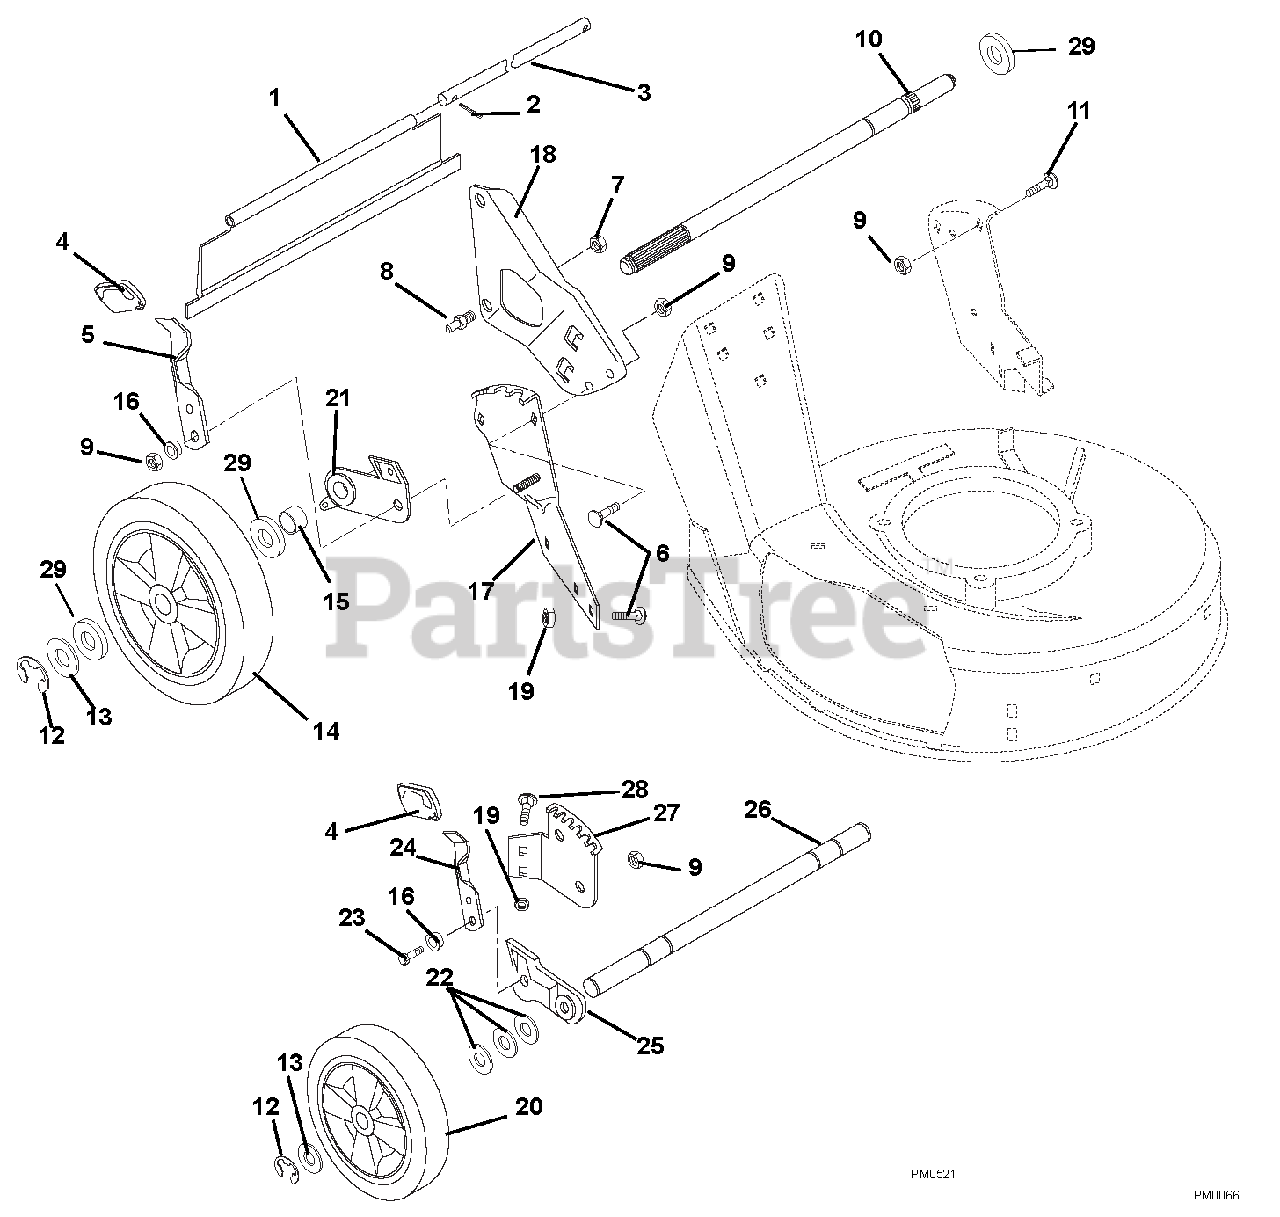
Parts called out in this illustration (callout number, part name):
1	REAR PROTECTIVE GUARD, S.P.
2	@PIN-CTR .06X.50 EXTPRSQCT YWZ
3	ROD
5	LEVER, HEIGHT ADJUSTMENT
6	@BLT-RHDSSQNK .31-18X.62 G5YZ
7	@NUT-LK-CTR .38-16 YWZC
8	HANDLEBAR STUD
9	@NUT-LK-TOP-FLG .31-18 YWZC
10	REAR AXLE,5/8 DIA
10	REAR AXLE-PUSH MOWER MM
11	BLT-RDHDSQNK .31-18X1.0 SHTYZ
12	RG-RTNG-EXT .500X.042 (E)
13	WSHR-FL-STL .505X.880X.072 YWZ
14	WHL, LH 10.50"
14	WHL, RH 10.50"
14	10 1/2 TIRE SKIN
14	TIRE, REAR 10X1.75 #6 GRAY
15	SPACER TUBE, SELF PROPEL
15	SPACER TUBE PUSH RH
16	BSHG-FLG .32X.500X.344X.880
17	QUADRANT, REAR LH
17	QUADRANT, REAR RH
18	RH HANDLEBAR MTG. BRKT
18	LH HANDLEBAR MTG. BRKT
19	@NUT-LK-TOP-FLG .31-18 YWZC
20	WHL 7.50" .50 BORE, 1.50 HUB
21	REAR ADJUSTMENT BRACKET L.H.
21	REAR BRACKET & BEARING ASSY RH
22	WSHR-FL-STL .52X.827X.062 YWZC
23	@BLT-HEX .31-18X1.00 GR5 YWZC
24	FRONT HEIGHT ADJUSTMENT LEVER
25	LEFT ADJUSTOR BRACKET ASSEMBLY
25	RIGHT ADJUSTOR BRACKET ASSEMBL
26	FRONT AXLE
27	FRONT QUADRANT, LH
27	FRONT QUADRANT, RH
28	@BLT-RDHDSQNK .31-18X.50 G5YZ
29	SPACER .531 X 1.00 X .225
